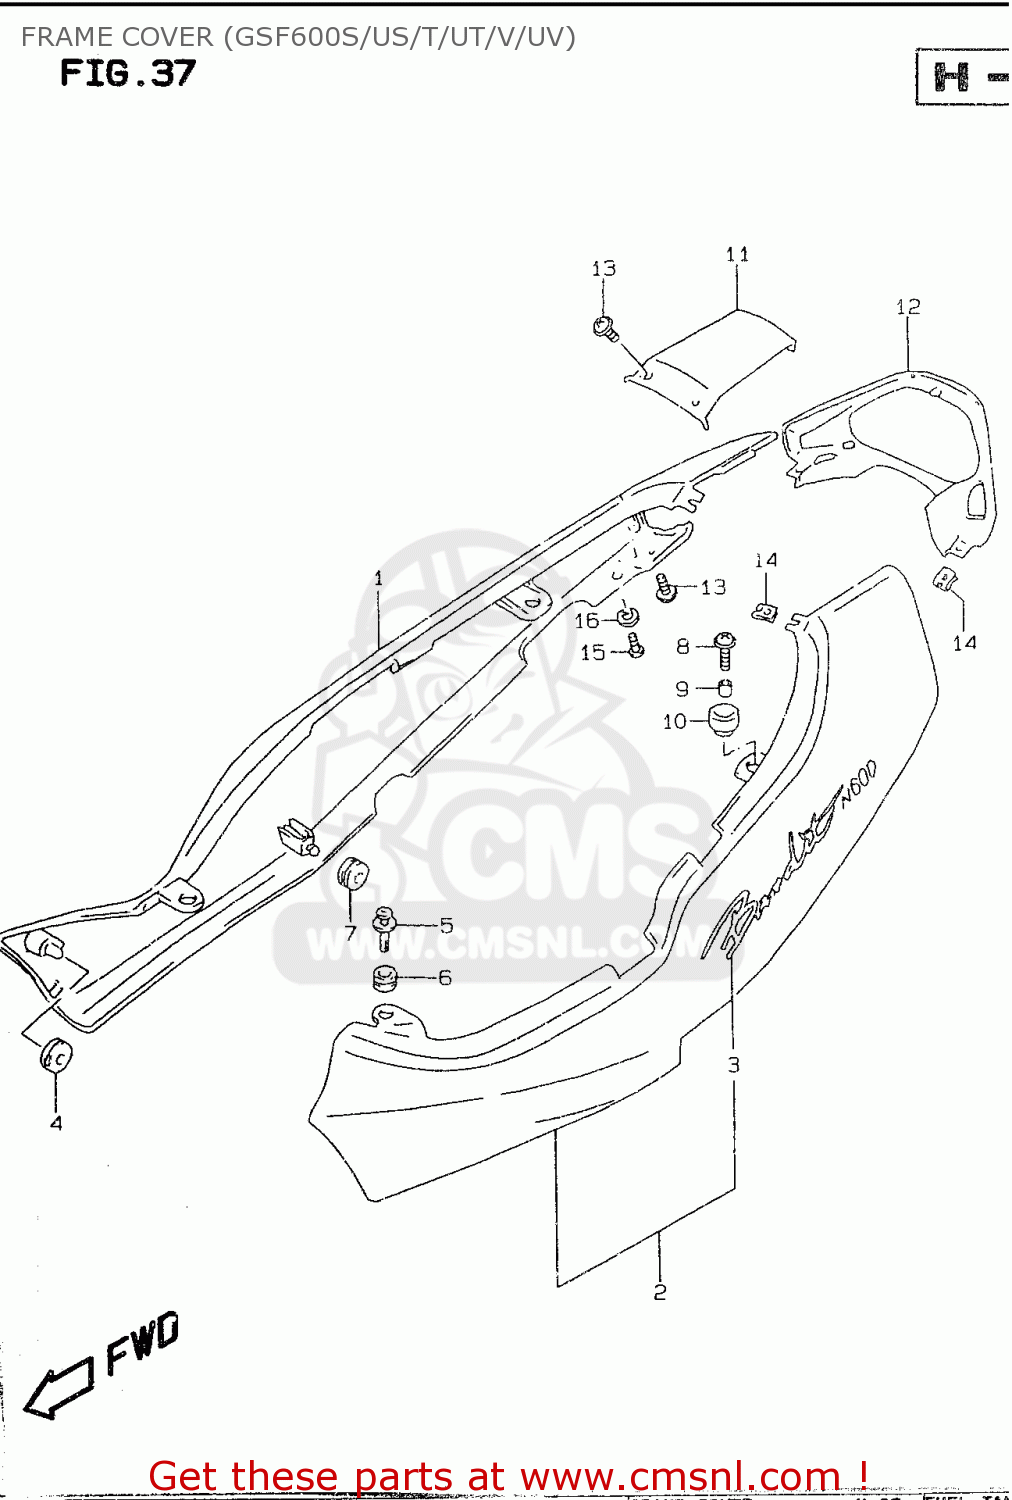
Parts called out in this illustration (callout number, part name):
1	COVER,FRAME,R
2	COVER,FRAME,L(GREEN)
3	EMBLEM,FRAME COVER
4	CUSHION,FRAME COVER FR
5	CLIP
6	CUSHION
7	CUSHION
8	SCREW(6X20)
9	SPACER(6.5X10X9.4)
10	CUSHION
11	COVER,FRAME CTR
12	COVER,FRAME RR
13	SCREW
14	NUT
15	SCREW
16	WASHER(6.3X16X1.5)
